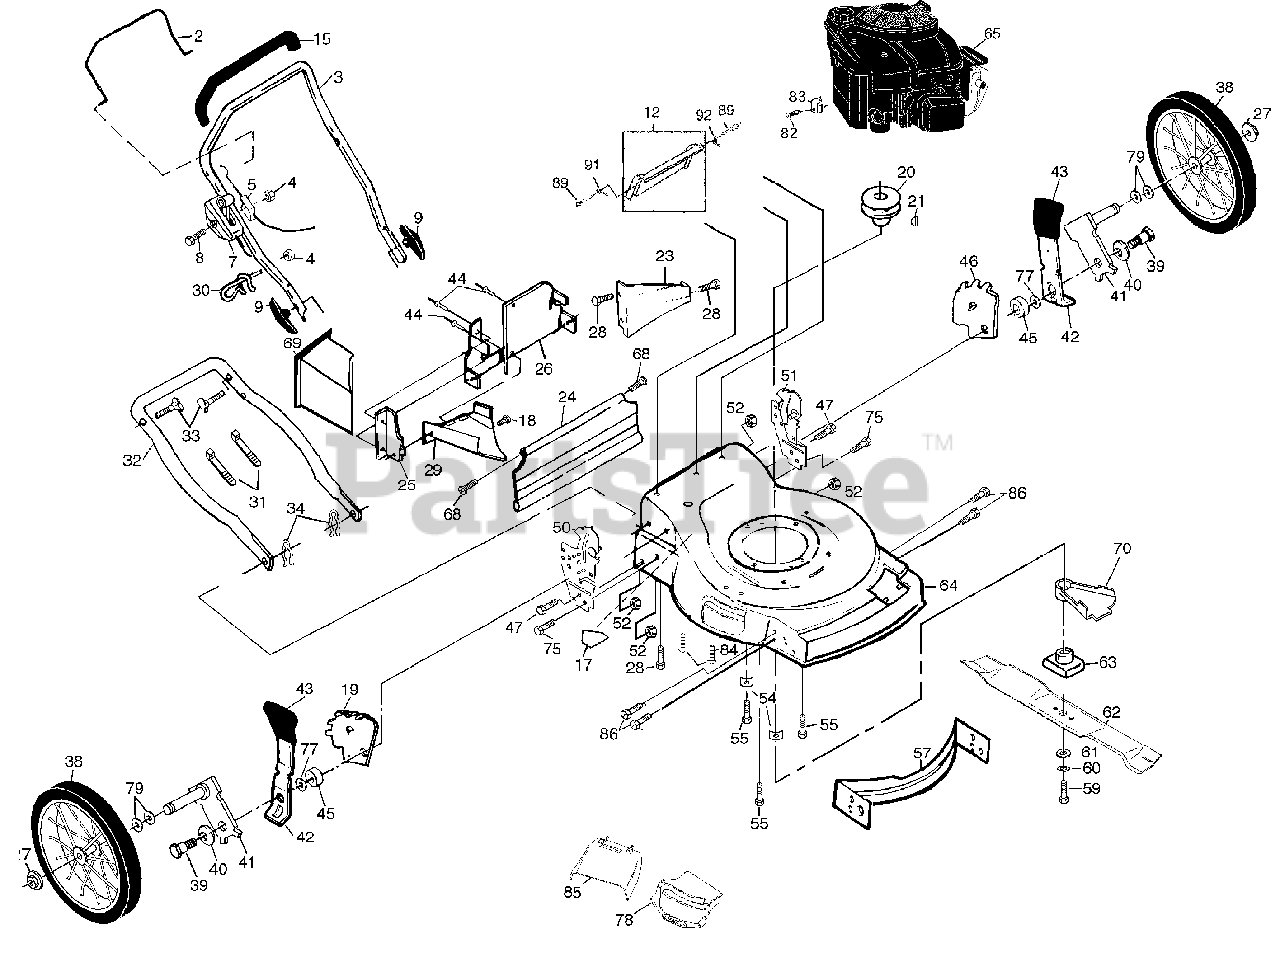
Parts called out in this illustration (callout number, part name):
2	Control Bar
3	Upper Handle
4	Locknut
5	Engine Zone Control Cable
7	Throttle Control
8	Hex Washer Head Screw 1/4-20 x 2-1/8
9	Handle Knob
12	Rear Door Kit
15	Handle Grip
17	Danger Decal
19	Wheel Adjusting Bracket
20	Engine Pulley
21	Hi Pro Key #505
23	Rear Baffle
24	Rear Skirt
25	Side Baffle
26	Back Plate
27	Flanged Locknut
28	Screw Hex Head 1/4-20 x 1/2
29	Discharge Baffle
30	Rope Guide
31	Wire Tie
32	Lower Handle
33	Handle Bolt
34	Hairpin Cotter
38	Wheel & Tire Assembly
39	Shoulder Bolt
40	Spring Washer
41	Axle Arm
42	Selector Spring
43	Selector Knob
45	Spacer
46	Wheel Adjusting Bracket
47	Self-tapping Screw 5/16-18 x 3/4
50	Handle Bracket (Right)
51	Handle Bracket (Left)
52	Locknut 3/8-16
55	Hex Head Thread Rolling Screw 3/8-16 x 1-1/8
57	Front Baffle
59	Hex Head Machine Screw 3/8-24 x 1-3/8 Gr. 8
60	Helical Lock Washer
61	Hardened Washer
63	Blade Adapter
64	Lawn Mower Housing Kit
68	Hinge Screw
69	Mulcher Plug
70	Debris Shield
77	Flat Washer
78	Combi-Cut Door Assm.
79	Wave Washer
83	Engine Clamp
84	Nut
85	Clip on Guard
89	Bolt
